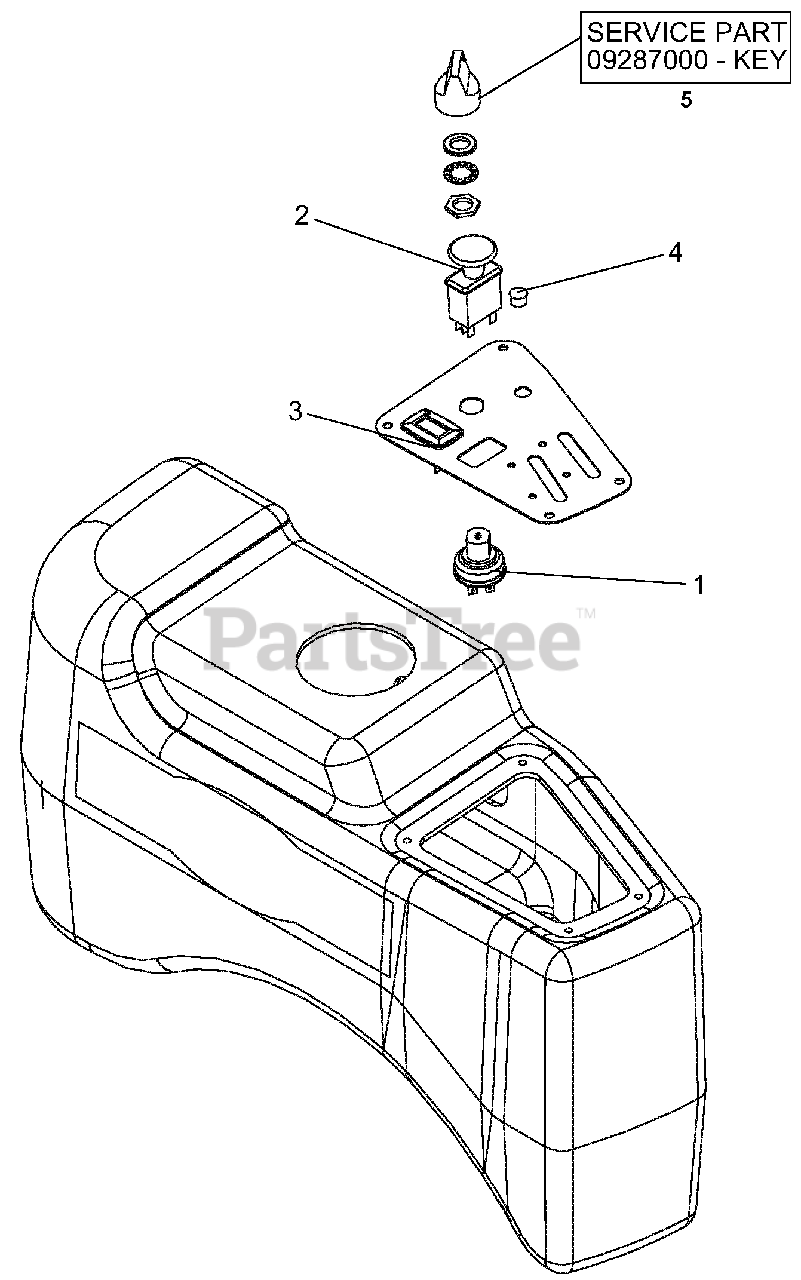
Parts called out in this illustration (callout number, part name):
1	SWITCH, IGNITION
2	SWITCH, CLUTCH
3	METER, HOUR W/MAINTENANCE
4	PLUG, HOLE .50 DIA
